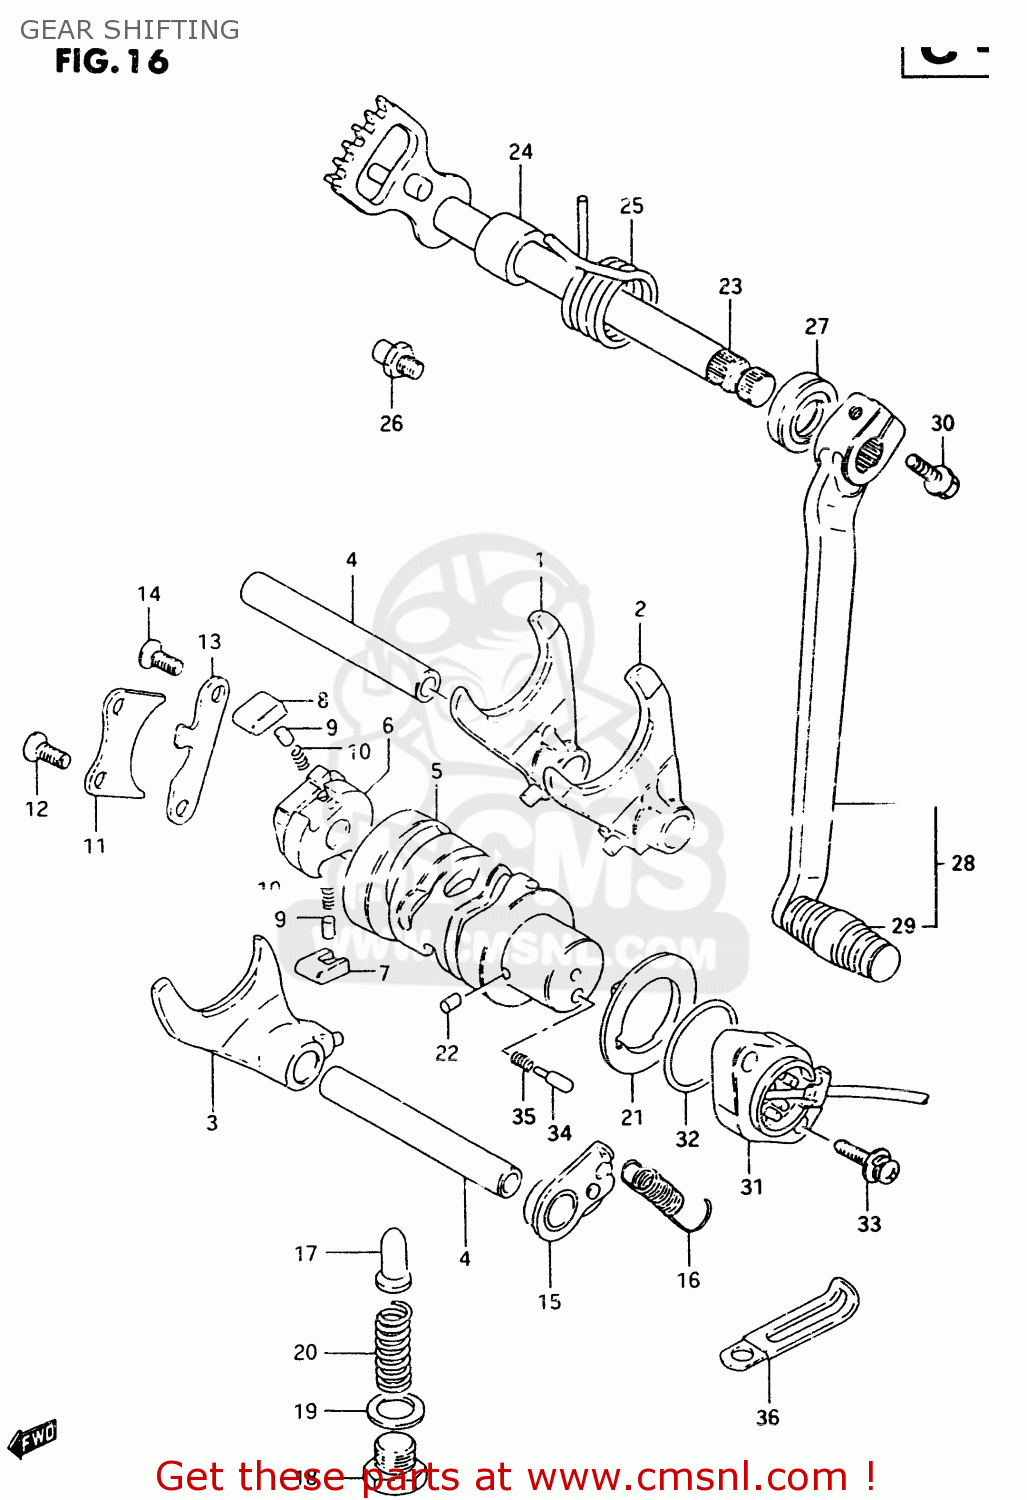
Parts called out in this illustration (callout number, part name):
1	FORK,GEAR SHIFT NO.1
2	FORK,GEAR SHIFT NO.2
3	FORK,GEAR SHIFT NO.3
4	SHAFT,GEAR SHIFT FORK
5	CAM,GEAR SHIFT
6	GEAR,GEARSHIFT CAM DRIVE
7	PAWL,GEAR SHIFT NO.1
8	PAWL,GEAR SHIFT NO.2
9	PIN(5X8)
10	SPRING
11	LIFTER,GEAR SHIFT POLE
12	SCREW
13	GUIDE,GEAR SHIFT CAM
14	SCREW
15	STOPPER,GEAR SHIFT CAM
16	SPRING
17	STOPPER,GEAR SHIFT CAM NO.2
18	PLUG(14X12)
19	GASKET(13.8X18.8X4.8) (NAS)
20	SPRING
21	PLATE,GEAR SHIFT CAM STOPPER
22	PIN
23	SHAFT,GEAR SHIFT
24	SPACER(12X20X15.3)
25	SPRING
26	STOPPER,GEAR SHIFT CAM
27	OIL SEAL
28	LEVER ASSY,GEAR SHIFT
29	RUBBER,GEAR SHIFT PEDAL
30	BOLT
31	BASE ASSY,NEUTRAL SW TERMINAL
32	O-RING (D:2.4 ID:26.2)
33	SCREW
34	PIN(5X15.5)
35	SPRING
36	CLAMP(L:65)
